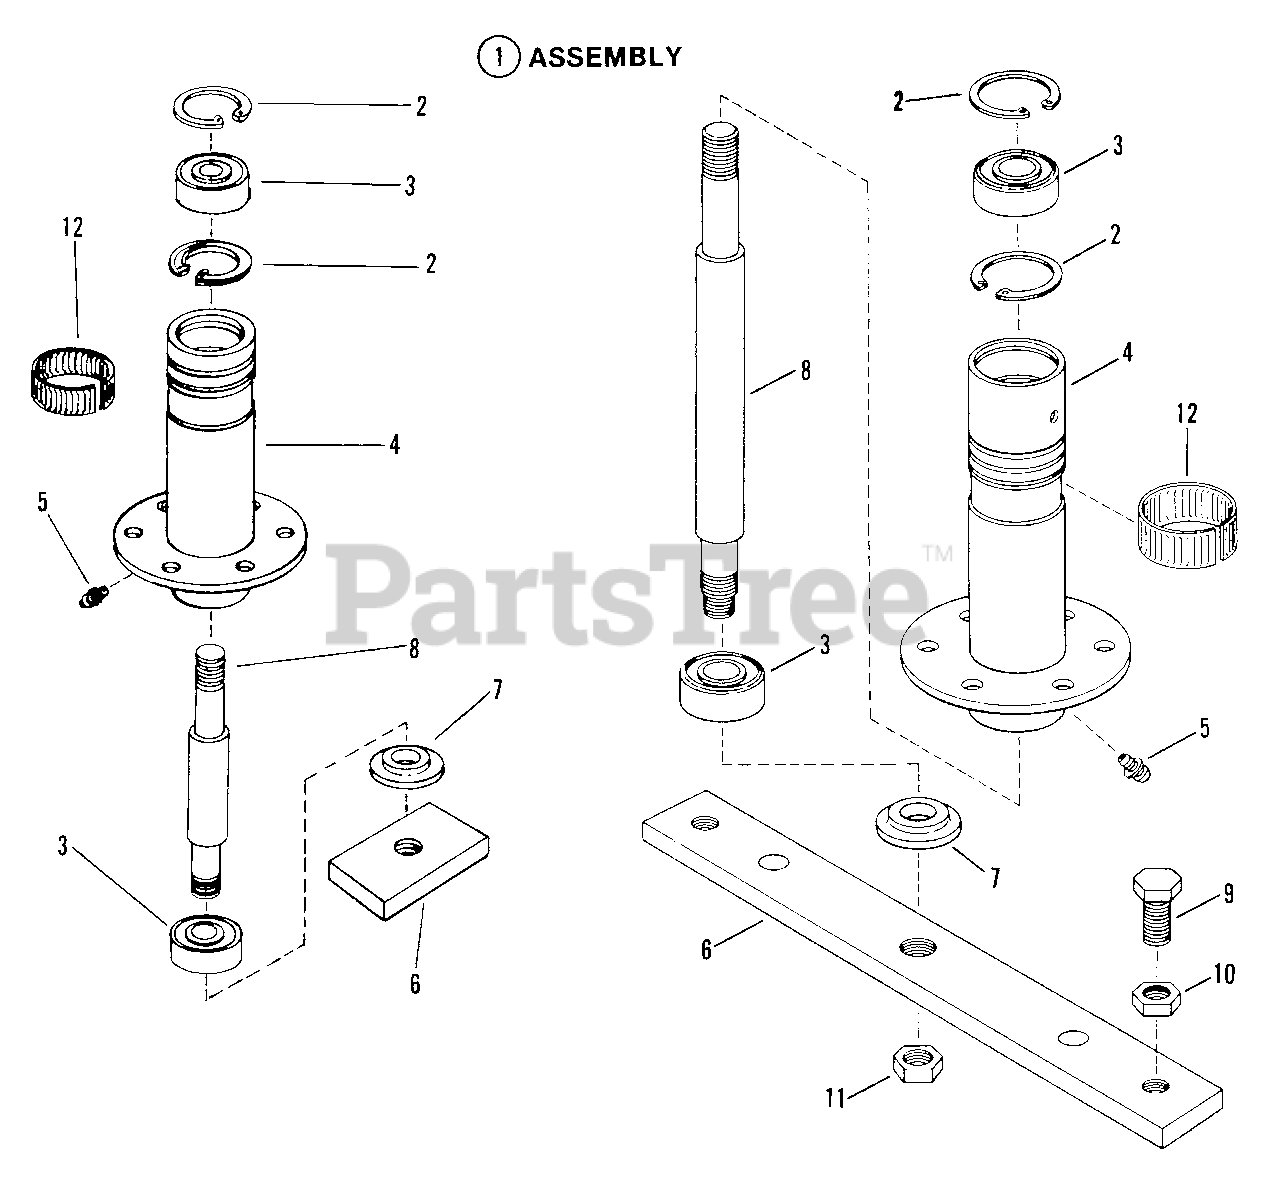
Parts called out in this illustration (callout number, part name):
1	ASSEMBLY, Spindle Housing
2	RING, Retaining
3	BEARING, Spindle
4	HOUSING, Spindle
5	FITTING, Lube (Press fit for .187 hole-no ball)
6	HOLDER, Blade
7	WASHER, Spindle
8	SPINDLE, Shaft (10.237" Long)
9	SCREW, 1/2-20x1 1/4" Hex Head Cap, Gr. 5
10	NUT, 1/2-20 Hex Jam
11	NUT, 5/8-18 hex Lock
12	RING, Tolerance
